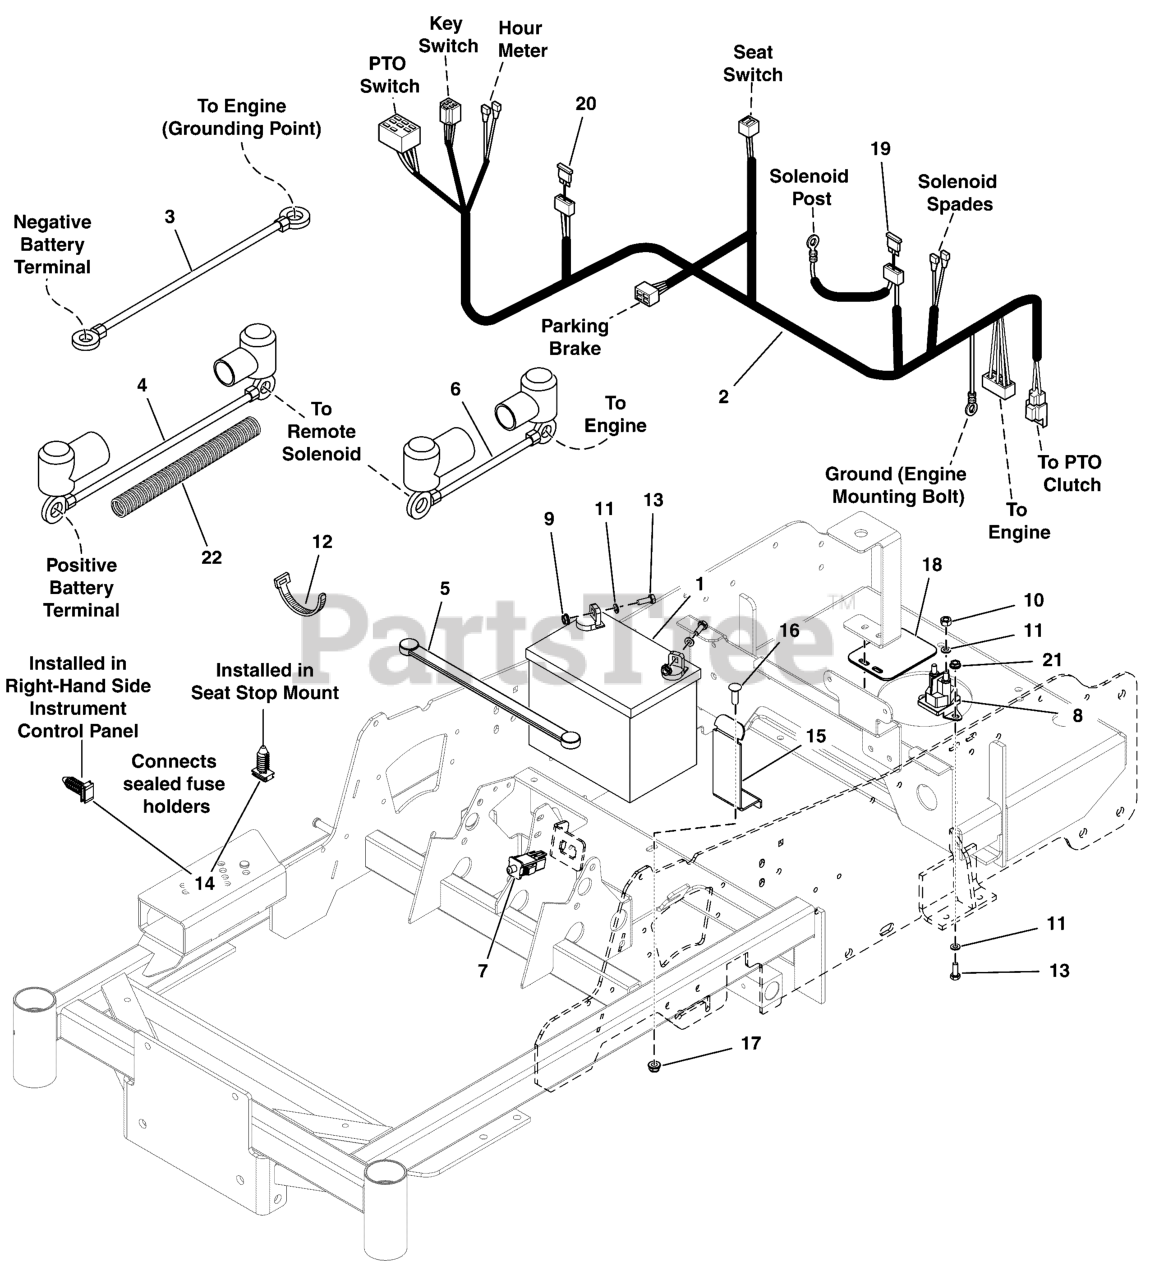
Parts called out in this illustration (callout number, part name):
1	BATTERY, WET ( BCIU1, 350 CCA)
2	WIRE HARNESS, MAIN, PROSUMER, NO NEUTRAL
2	WIRE HARNESS, MAIN, SM, ZTR
2	HARNESS, Wiring, Small ZTR
3	CABLE, BATTERY, NEG, 30, 1/4-5/16
4	BATTERY CABLE, POS, 22, 1/4-5/16
5	STRAP, BATTERY, 14 LONG, Rubber
6	BATTERY CABLE, POS, 8, 1/4-5/16
7	SWITCH, DP NO/NC SNAP-IN
8	SOLENOID, STD-BRACKET, 2-SPADE
9	NUT, 1/4-20 HEX SERR. FLANGE
10	NUT,1/4-20,KEPS,CONICAL WSHR,ZC/CL
11	WASHER, 1/4 SAE
12	TIE, SELF-LOCKING, 12"
13	HHCS, 1/4-20 X 0.625, GR5, ZINC/CLEAR
14	FIR TREE MOUNT, PACKARD
15	PLATE, HARNESS/BATTERY SUPPORT - BLK
16	BOLT, 5/16-18 X 1, CARRIAGE, GD5, CZ
17	NUT, 5/16-18 HEX NYLOCK FLANGE NUT
18	PLATE, SOLENOID COVER - BLK
19	FUSE, ATO-20 (20 AMP)(SV)
20	FUSE, ATO-15 (15 AMP)(SV)
21	NUT, 1/4-20 Hex Nylock Flange
22	WIRE LOOM, 3/8 ID X 18 IN
